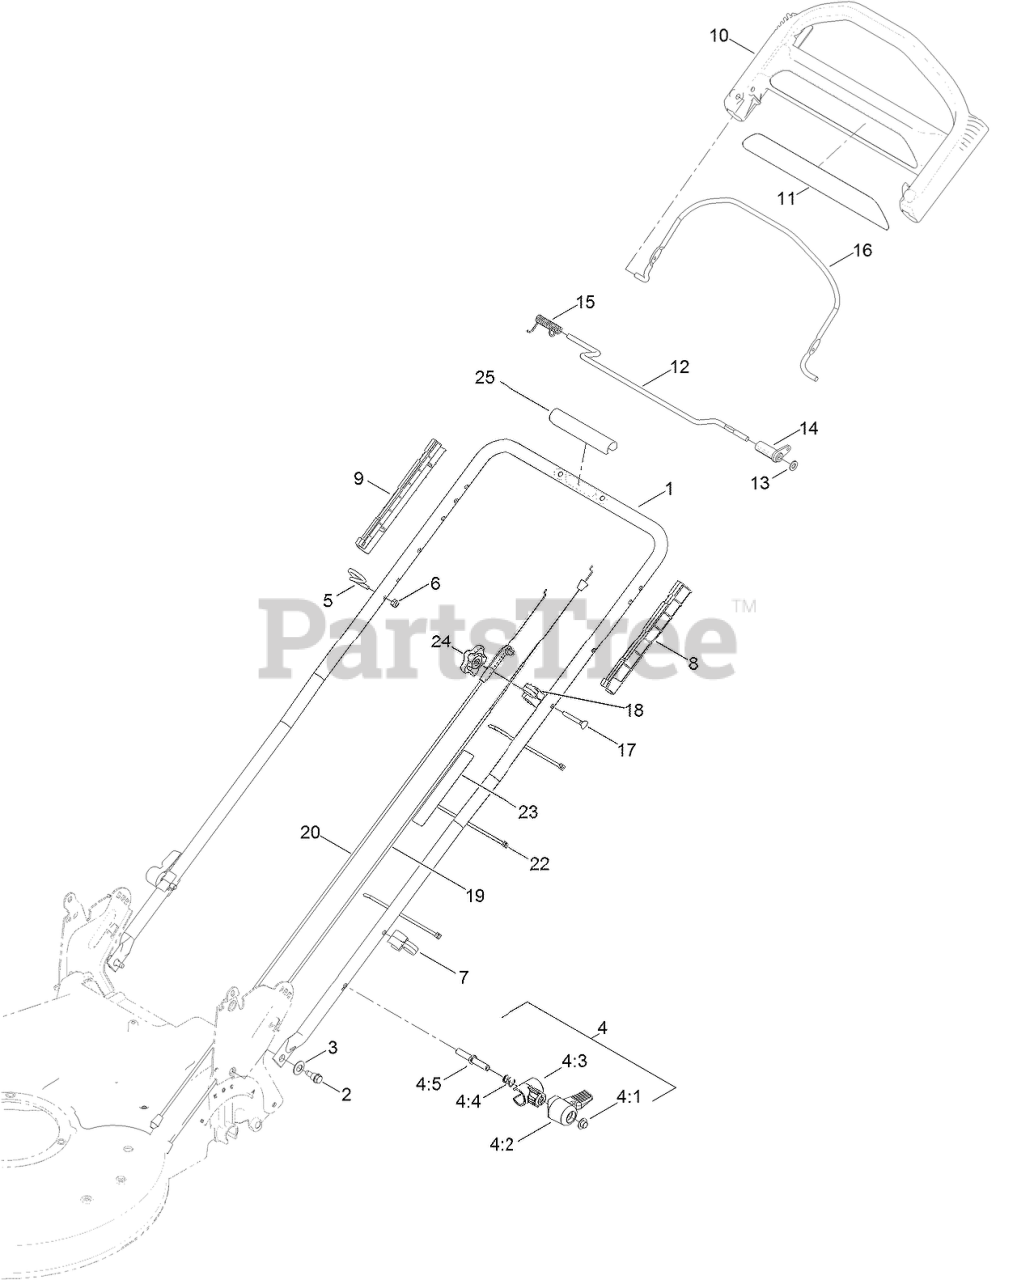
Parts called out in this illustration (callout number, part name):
2	BOLT-SHOULDER
3	WASHER-SPRING, CONICAL
4	QUICK RELEASE ASM
4:1	NUT-PUSH
4:2	LEVER
4:4	SPRING-COMPRESSION
4:5	ROD-RELEASE
5	GUIDE-ROPE
6	NUT-LOCK, NI
7	GUIDE-CABLE
8	GUIDE-LH
9	GUIDE-RH
10	HANDLE-CONTROL
11	DECAL-HANDLE
12	BAR-CONTROL, TRACTION
13	WASHER-PLAIN
14	LEVER-TRACTION
15	Spring-Torsion
16	BAIL-BRAKE
17	SCREW
18	ANCHOR-CABLE
19	CABLE-TRACTION
20	CABLE-BRAKE
22	TIE-CABLE
23	DECAL-TRACTION, ADJUST
24	KNOB-HANDLE, LOCKING
25	HANDLE-COVER
